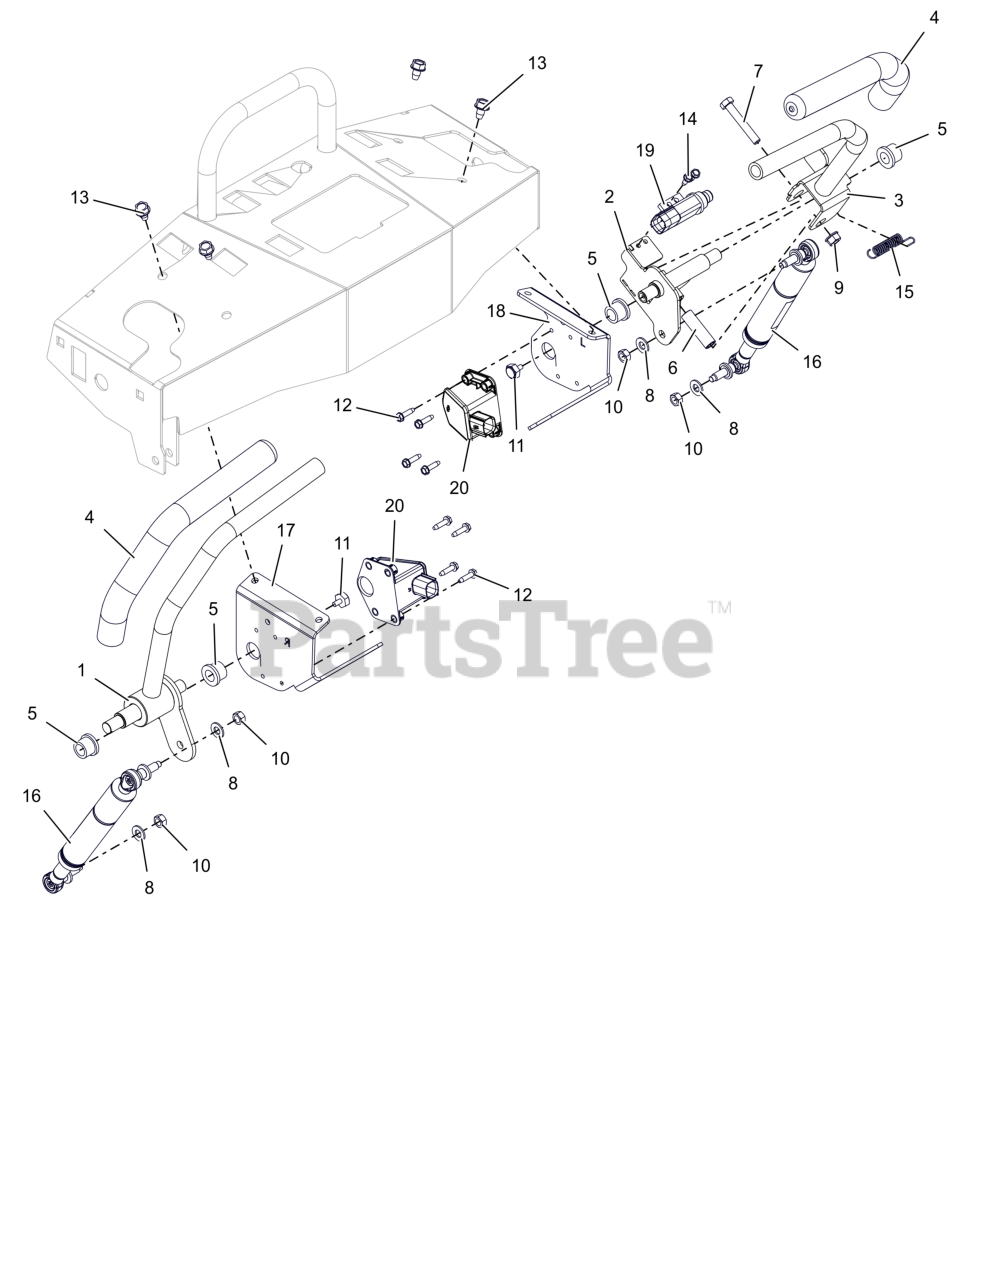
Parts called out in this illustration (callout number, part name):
1	WLDMT- RH DRIVE CONTROL
2	WLDMT- LH DRIVE CONTROL
3	WLDMT- LH HANDLE ASM
4	GRIP, HANDLEBAR
5	BSHG, FLG .516X.750X.625X.937
6	BSHG- SLV
7	BLT, HEX .31-18X2.00 G5 ZCC
8	WSHR, HRDN 0.344X0.688X0.065
9	NUT,LK-CTR-FLG .31-18 GF ZCC
10	NUT-HEX-JAM-CTR LK M8X1.25 ZCC
11	BOLT, MAGNETIC STEERING SENSOR
12	SCR, TAP #10-24X.75 HWH ZCC
13	SCR,TAP .312-18X.50 HWH TR ZCC
14	SCR,TAP #10-24X.50 HWH TR ZCC
15	SPRING, EXT. .043X.438X1.64
16	DAMPER, NEUTRALIZING
17	BRKT- RH DRIVE CONTROL MTG
18	BRKT- LH DRIVE CONTROL MTG
19	SWITCH, SEALED PLUNGER
20	SENSOR, STEERING
